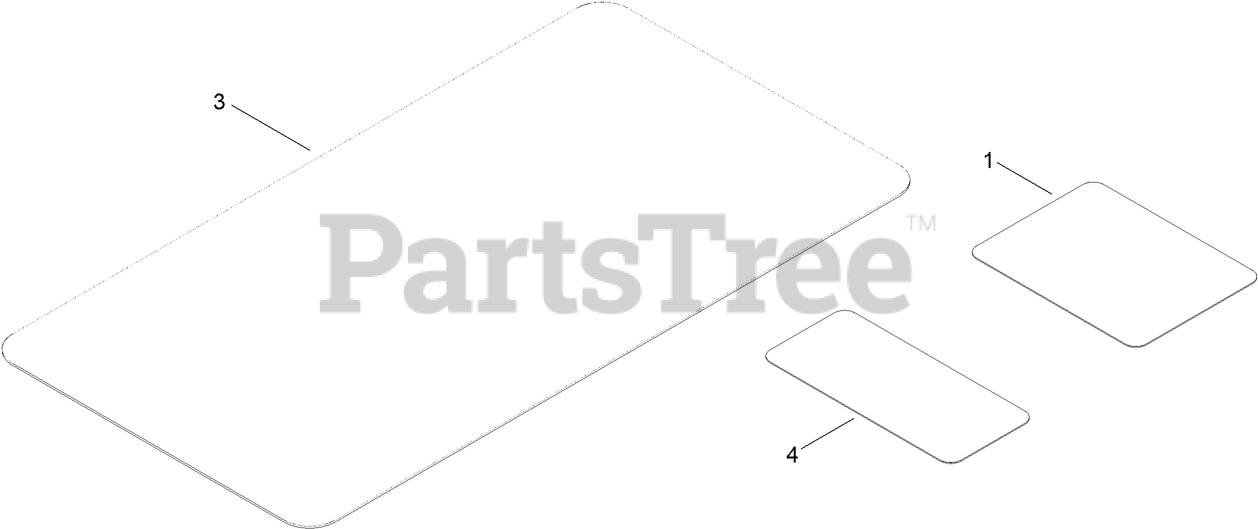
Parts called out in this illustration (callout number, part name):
1	DECAL-MAINTENANCE
3	DECAL-HOC
4	DECAL-LOCATION, SERVICE DEALER
